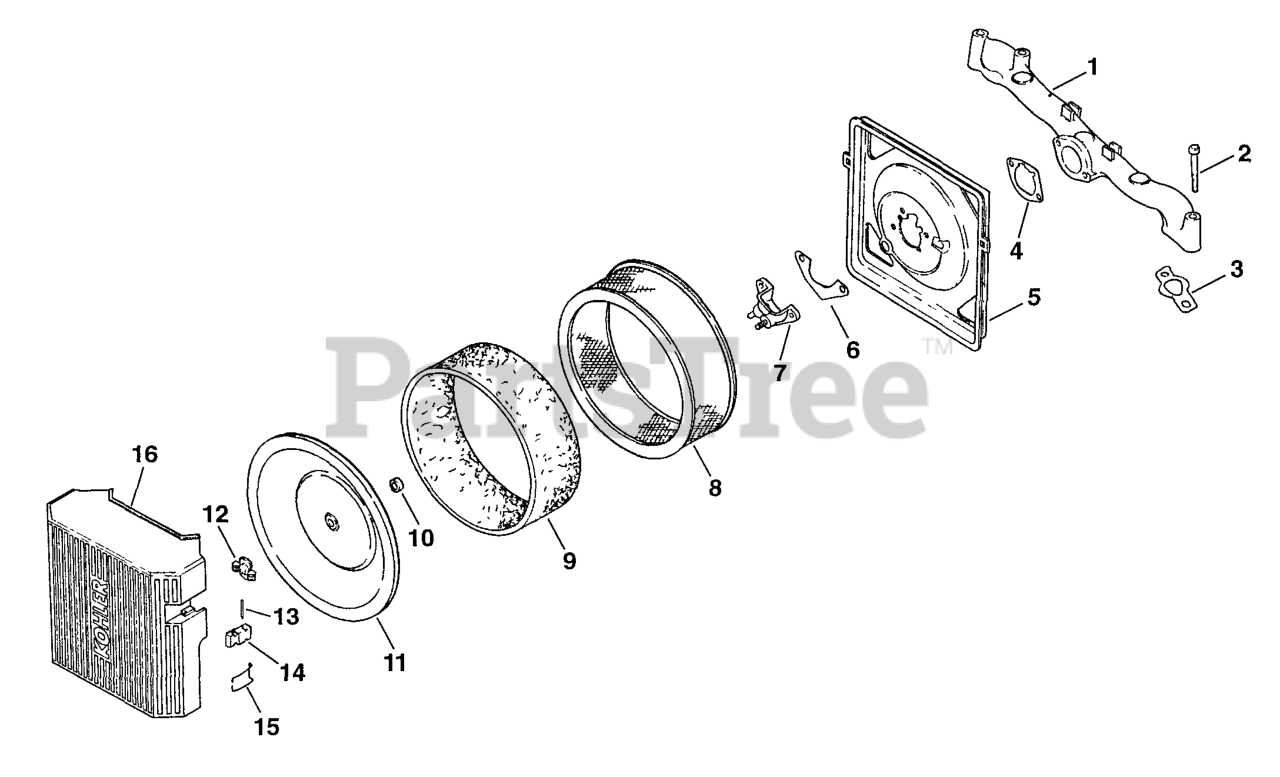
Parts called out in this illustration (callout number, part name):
1	MANIFOLD, INTAKE
2	Screw, hex. flange M6x1.0x55
3	GASKET, INTAKE MANIFOLD USE 24 041 79-S
4	GASKET, AIR CLEANER BASE
5	KIT - USE 24 755 86
6	GASKET, FUEL SPITBACK CUP
7	KIT - USE 24 755 86
8	ELEMENT, AIR CLEANER - Also available Retail Packaged 47 883 03-S1 Air Filter Kit
9	ELEMENT, PRECLEANER (LOW)
10	SEAL, INNER AIR CLEANER
11	COVER, INNER AIR CLEANER
12	NUT, WING
13	PIN DISCONTINUED
14	LATCH, LEVER - DISCONTINUED
15	SPRING, LATCH - DISCONTINUED
16	KIT - USE 24 743 05
